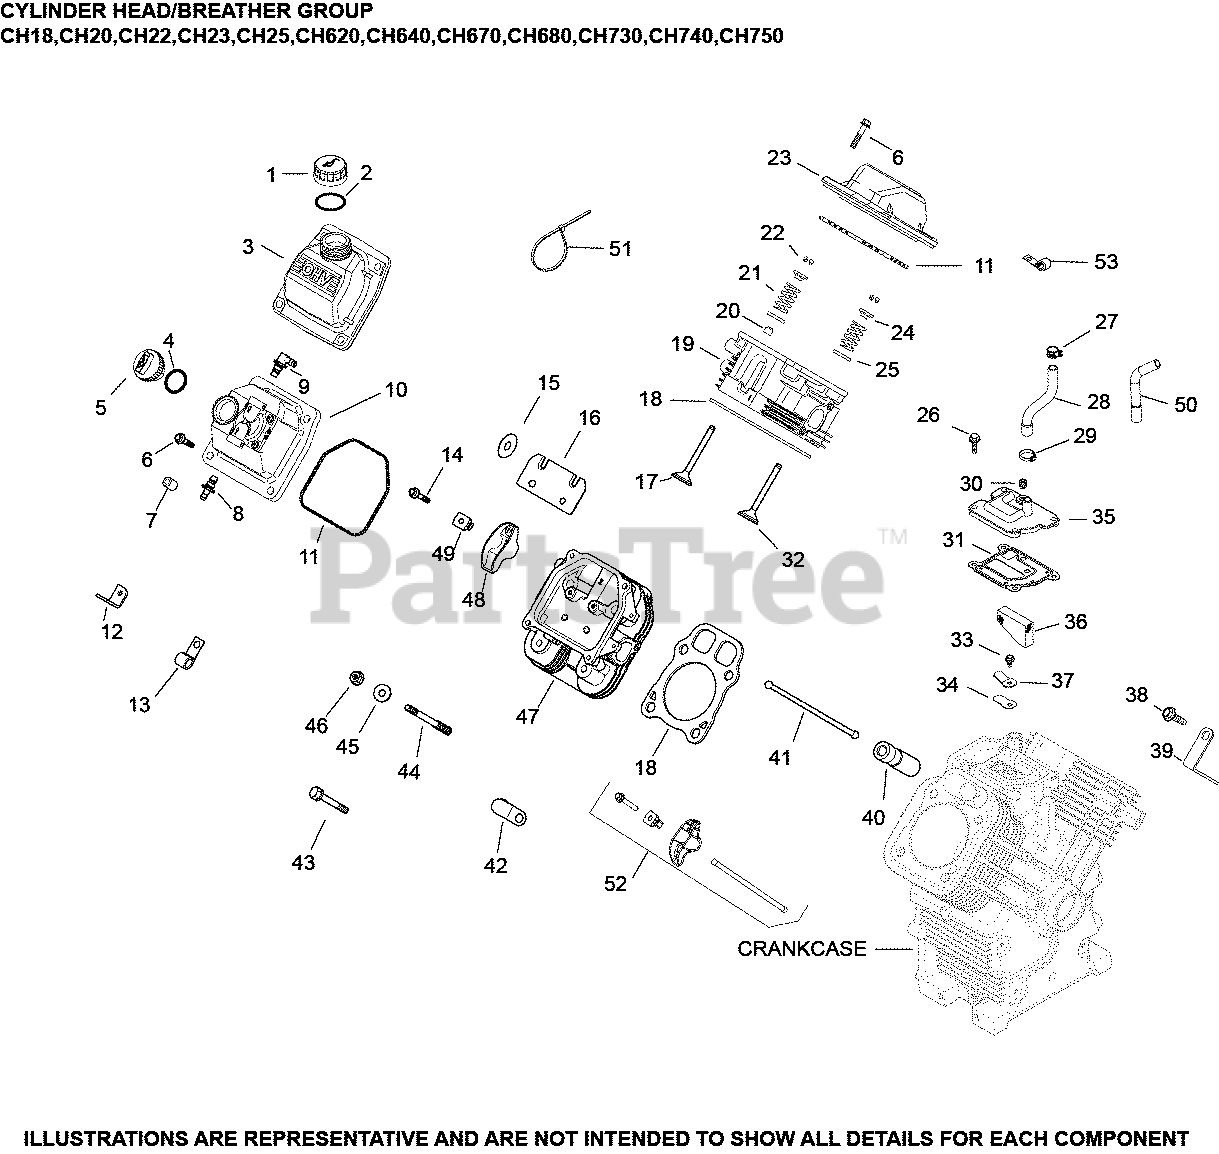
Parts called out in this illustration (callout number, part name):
4	O-RING-USE 24 153 32-S
5	CAP ASSY, OIL FILL (YELLOW)
6	SCREW, FLG M6X1.0X30
8	KIT, STRAIGHT FITTING
9	KIT, 90 DEG. FITTING
10	KIT, VALVE COVER-FUEL PUMP
11	O-RING (YELLOW), VALVE COVER
14	SCREW, FLG M6X1.0X34
17	VALVE, EXHAUST (STD) - USE 32 016 01-S
17	VALVE, EXHAUST (.25)
18	KIT, CYLINDER HEAD GASKET
19	KIT, #1 CYLINDER HEAD USE 24 318 171-S
20	SEAL, VALVE BAND
21	SPRING, VALVE
22	KIT, RETAINER
23	KIT, VALVE COVER-PLAIN (PLASTIC)
24	CAP, VALVE SPRING
25	RETAINER, SPRING
26	SCREW, THREAD FORMING
27	CLAMP SPRING HOSE
28	HOSE, BREATHER
31	GASKET, BREATHER
32	VALVE, INTAKE (STD)
32	VALVE, INTAKE (.25)
33	SCREW, FLG THD FRM M5X.8X10
34	REED, BREATHER
35	KIT, BREATHER ASSEMBLY
36	FILTER, BREATHER
37	RETAINER, REED
38	SCREW, THREAD FORMING
39	STRAP, LIFT
40	LIFTER, HYDRAULIC VALVE-USE 25 351 10-S
41	ROD, PUSH
44	STUD, M8X1.25
45	WASHER, FLAT 8.6 MM
46	NUT, FLG M8X1.25
47	KIT, #2 CYLINDER HEAD USE 24 318 172-S
48	ARM, ROCKER
49	PIVOT, ROCKER ARM
52	KIT, VALVE TRAIN
24755147-S	KIT, CYLINDER HEAD HARDWARE
